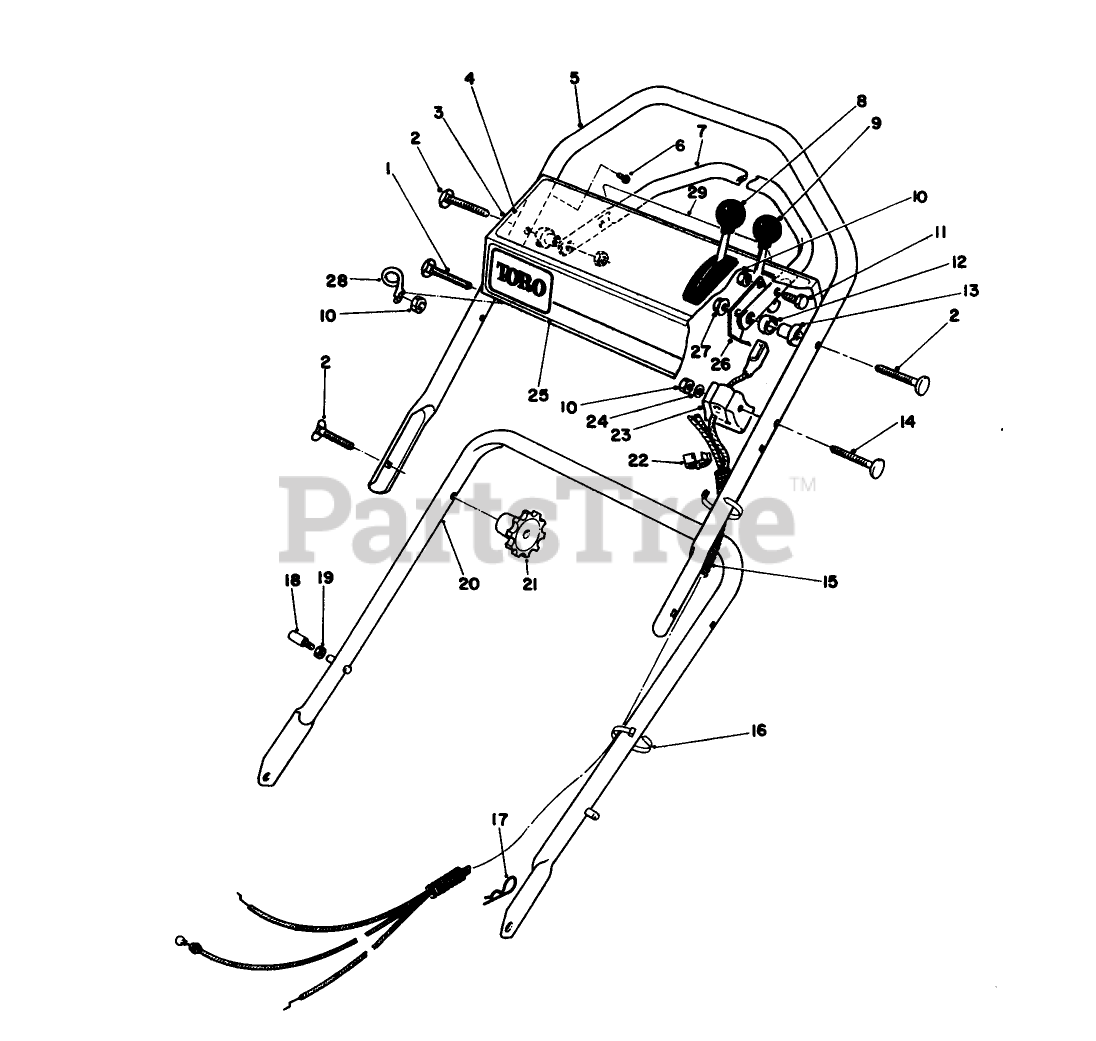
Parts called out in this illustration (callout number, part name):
1	HANDLE SCREW
6	SCREW-HWHTF
10	NUT-LOCK, NI
11	SCREW-HH
12	SPACER-NYLON
13	SPACER-SUPPORT
14	HANDLE SCREW
16	TIE-CABLE
17	PIN-COTTER, HAIR
19	NUT-LOCK, NI
20	LOWER HANDLE ASM
22	FITTING-RING
23	SUPPORT-CABLE
24	WASHER-FLAT
26	LEVER-CONTROL
27	NUT-LOCK, NI
